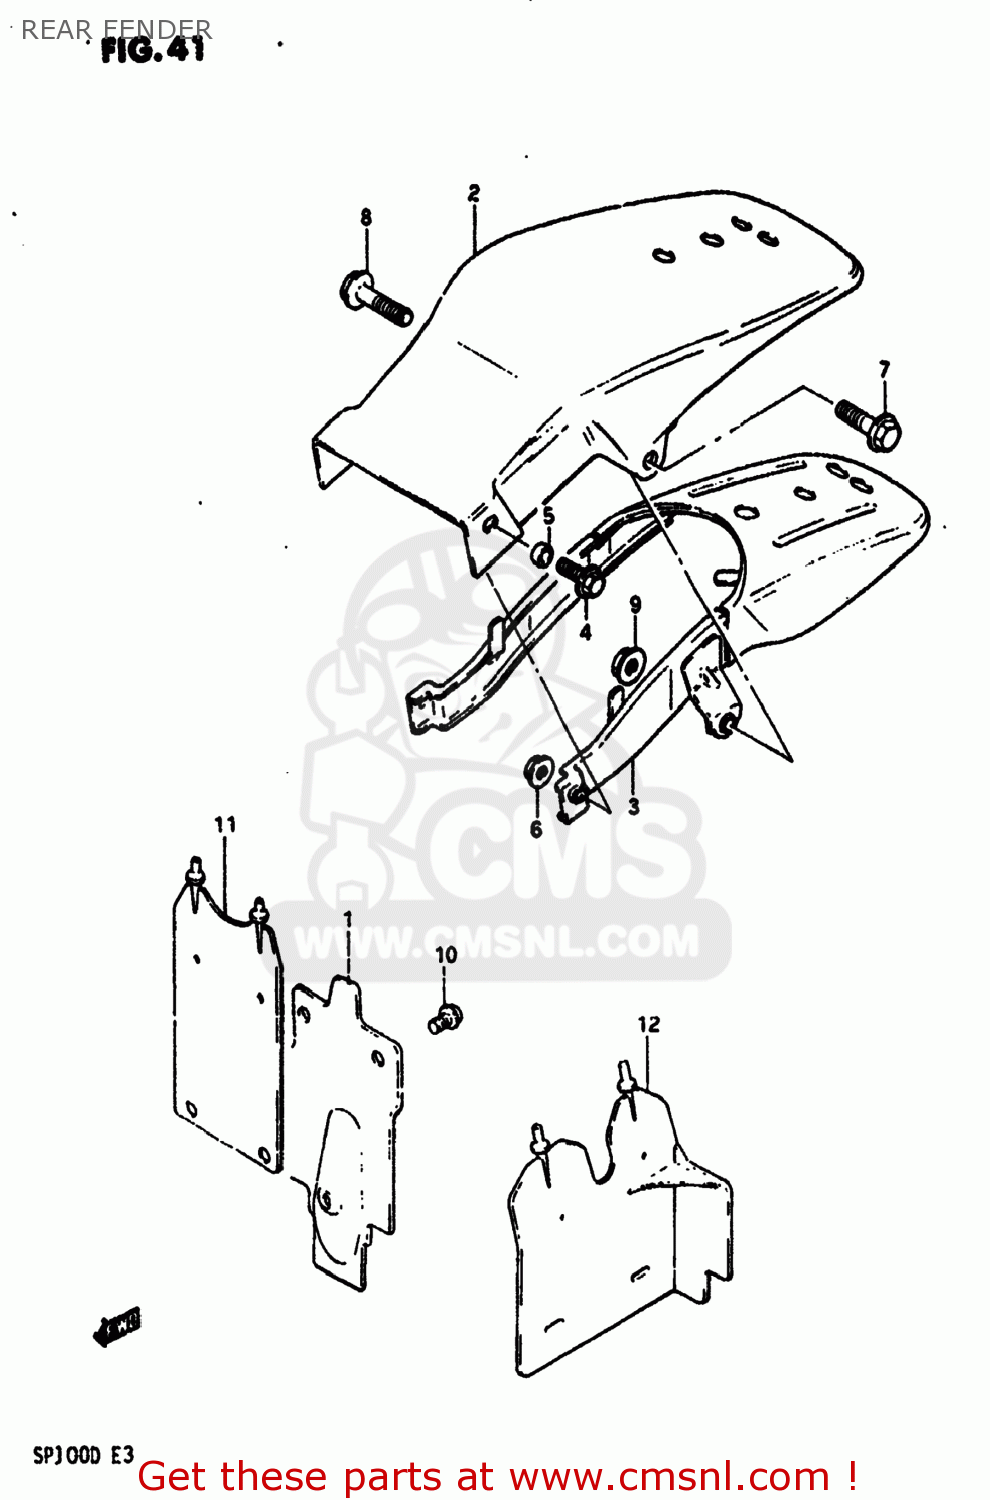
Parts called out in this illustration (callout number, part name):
1	REAR FENDER,FRONT
2	FENDER,REAR
3	REINFORCEMENT,REAR FENDER
4	BOLT,REAR
5	SPACER
6	NUT
7	BOLT
8	BOLT
9	NUT
10	SCREW, FRONT
11	MUD GUARD,REAR FENDER
12	MUD GUARD
